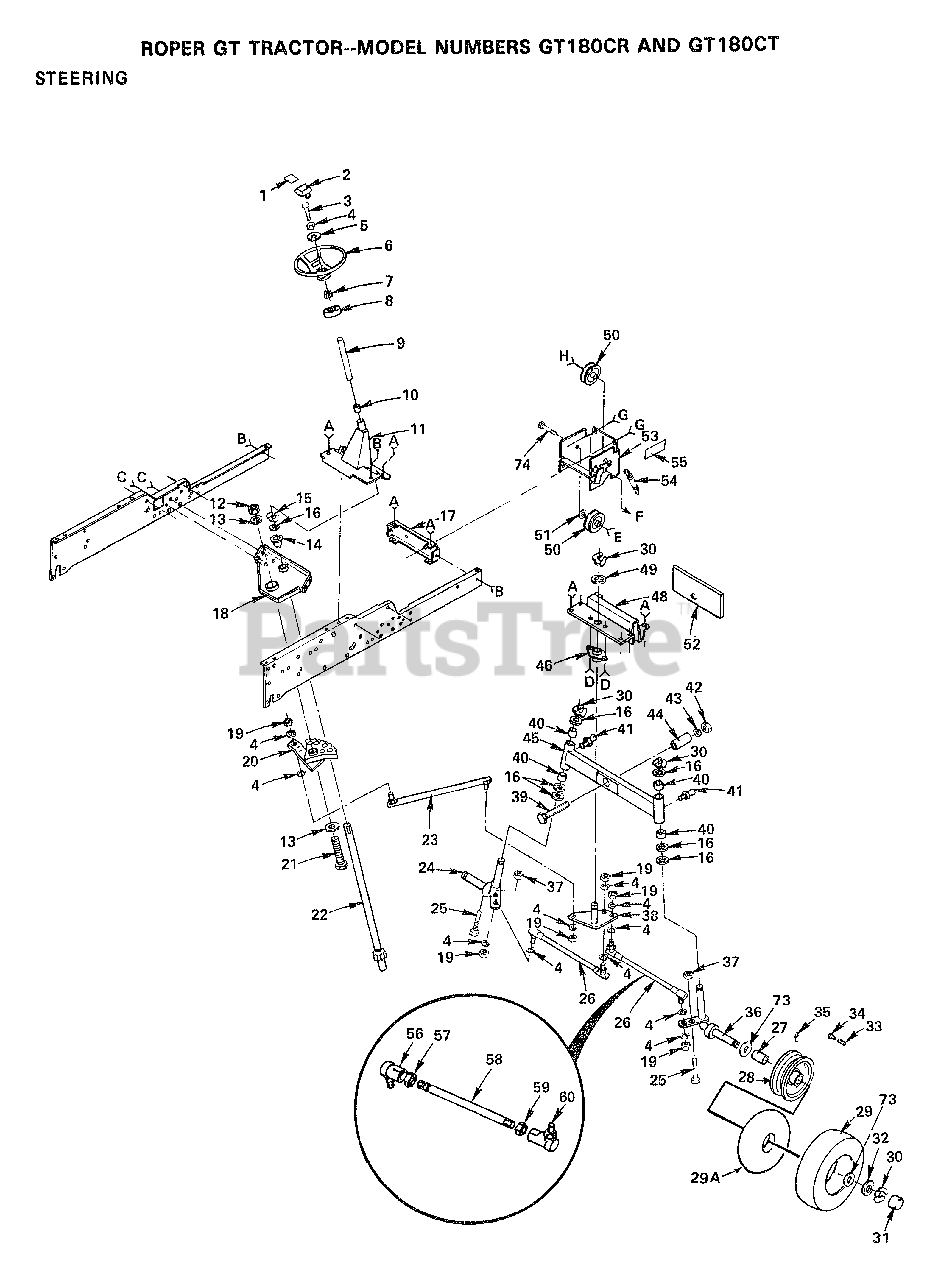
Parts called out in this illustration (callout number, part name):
1	DECAL - STEERING WHEEL
2	INSERT-WHEEL LT
3	BOLT
4	LOCKWASHER
5	WASHER T
7	ADAPTER LT
9	TUBE
10	"T, BEARING"
11	SUPPORT ASSY T
12	NUT LTV
13	WASHER GT
14	"FLANGE GT, BEAR."
15	KLIP RING
16	WASHER .T
17	FRAME BRACKET GT
21	BOLT
22	SHAFT STEERING GT
24	SPINDLE ASSY T
25	BOLT, HEX 3/8 - 16 X 2
27	"FLANGE, BEARING"
29A	TUBE.16X6.5/7.5-8
30	RING
31	HUB CAP
33	VALVE CAP
34	VALVE STEM LT
35	FITTING LT
36	SPINDLE RH T
37	NUT
38	"T, BELLCRANK"
39	BOLT
40	BRNG. T
41	ZERK M
42	NUT X
43	WASHER
45	AXLE ASSEMBLY
48	AXLE BRACKET T
49	WASHER
50	IDLER-INSIDE T
51	WASHER T
54	SPRING
57	NUT
59	NUT
